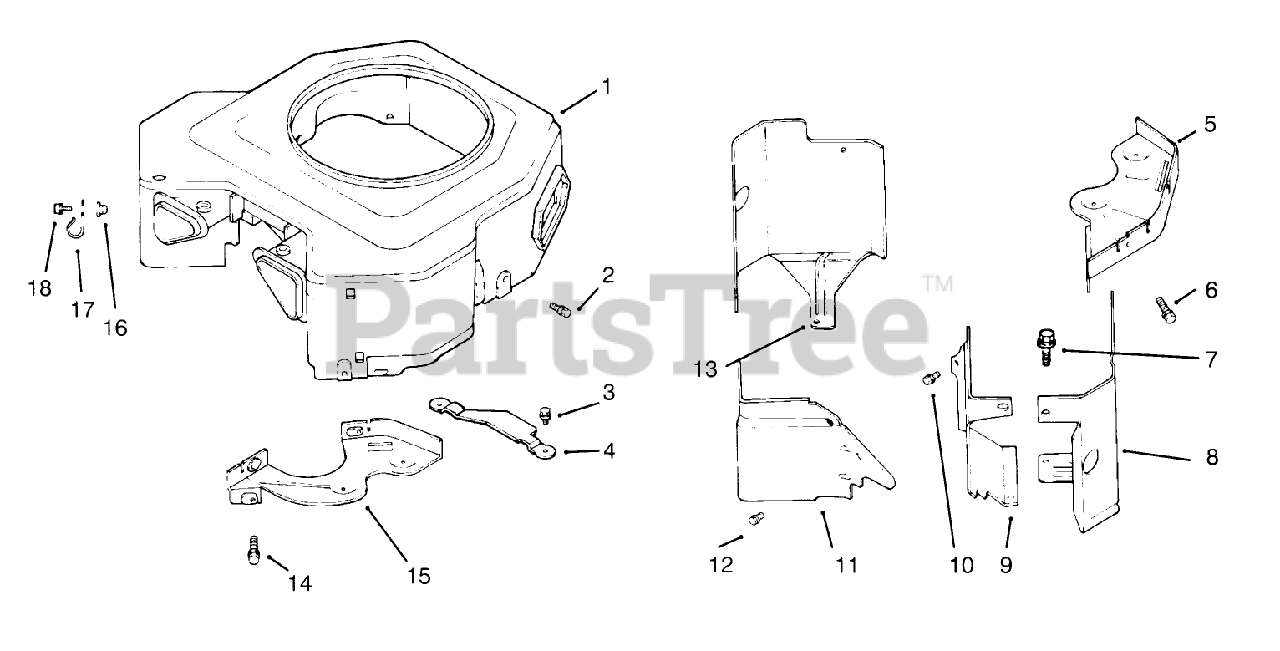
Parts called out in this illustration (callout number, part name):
1	Housing-Blower ASM (Only C)n: 72103, 72083)
4	Guard-Flywheel (Only On: 72103, 72083)
5	Plate-Backing #2 side
8	Baffle Cylinder #2 Side
9	Baffle-Valley #1 Side (Only On: 72103)
11	Baffle-Valley #2 Side (Only On: 72103, 72083)
13	Baffle-Cylinder #1 Side (Only On: 72103)
15	Plate-Backing #1 Side (Only On: 72103, 72083)
17	Clip-Cable (Only On: 72103)
